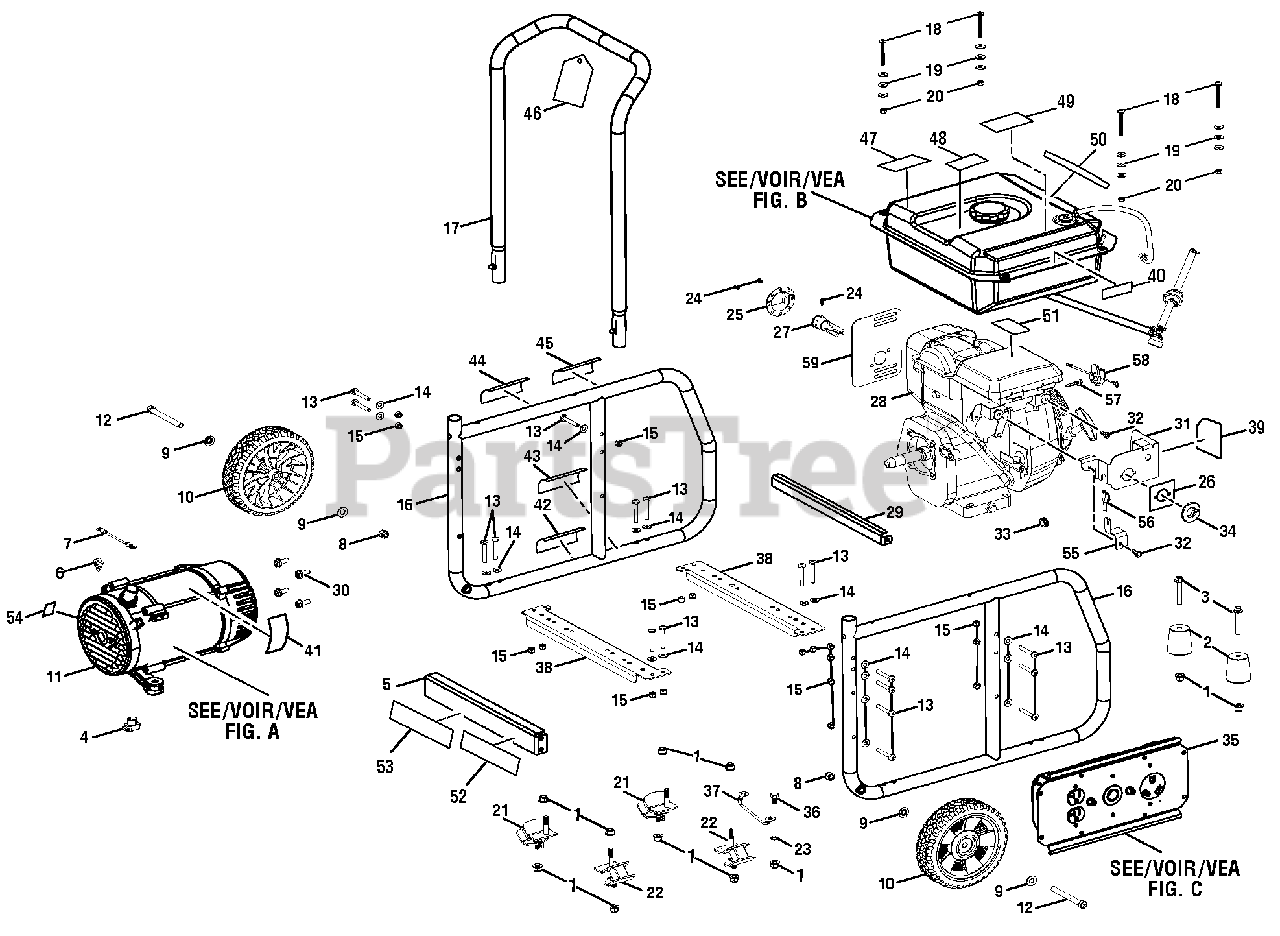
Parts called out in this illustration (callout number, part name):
1	Nut (M8 x 1.25 in.)
2	Rubber Foot
3	Bolt (M8 x 50 mm)
4	Rubber Plug
5	Fuel Tank Support (Rear)
6	Ground Lug
7	Bonding Wire
8	Nut (3/8 in.)
9	Washer (3/8 in.)
11	Generator Head Assembly (See Fig. A)
12	Axle Bolt
13	Bolt (1/4-20 x 1.675 in.)
14	Washer (1/4 in.)
15	Nut (1/4-20)
16	Frame Assembly
18	Bolt (M6 x 50 mm, T-30 Torx Hd.)
19	Washer (M6)
21	Engine Isolator (Left)
22	Engine Isolator (Right)
23	Star Washer (M8)
24	Screw (8-32 x 3/8 in.)
25	Exhaust Deflector
26	Fuel Valve Label
27	Spark Screen
29	Fuel Tank Support (Front)
30	Bolt (5/16-24 x 0.75 in.)
32	Bolt (M6 x 16 mm)
33	Rubber Grommet
34	Fuel Valve Bezel
35	Control Panel Assembly (See Fig. C)
36	Bolt (M8 x 15 mm, Hex Hd.)
37	Ground Wire Assembly
38	Engine Brace
39	Engine Switch Label
40	Fire Danger Label
41	Data Label
42	Inquiries Label
43	Check Oil Label
44	Hot Surface Label
45	Fire Distance Label
46	Warning Hangtag
47	Warning Label
48	E85 Label
49	CPSC Label
50	Logo Label
51	Engine Start Label
52	Ground Warning Label
53	Combustion Label
54	Ground Label
55	Vapor Adaptor Bracket
56	Vapor Adaptor
57	Screw (#10-16 x 3/4 in.)
58	Engine Switch
59	Heat Shield
